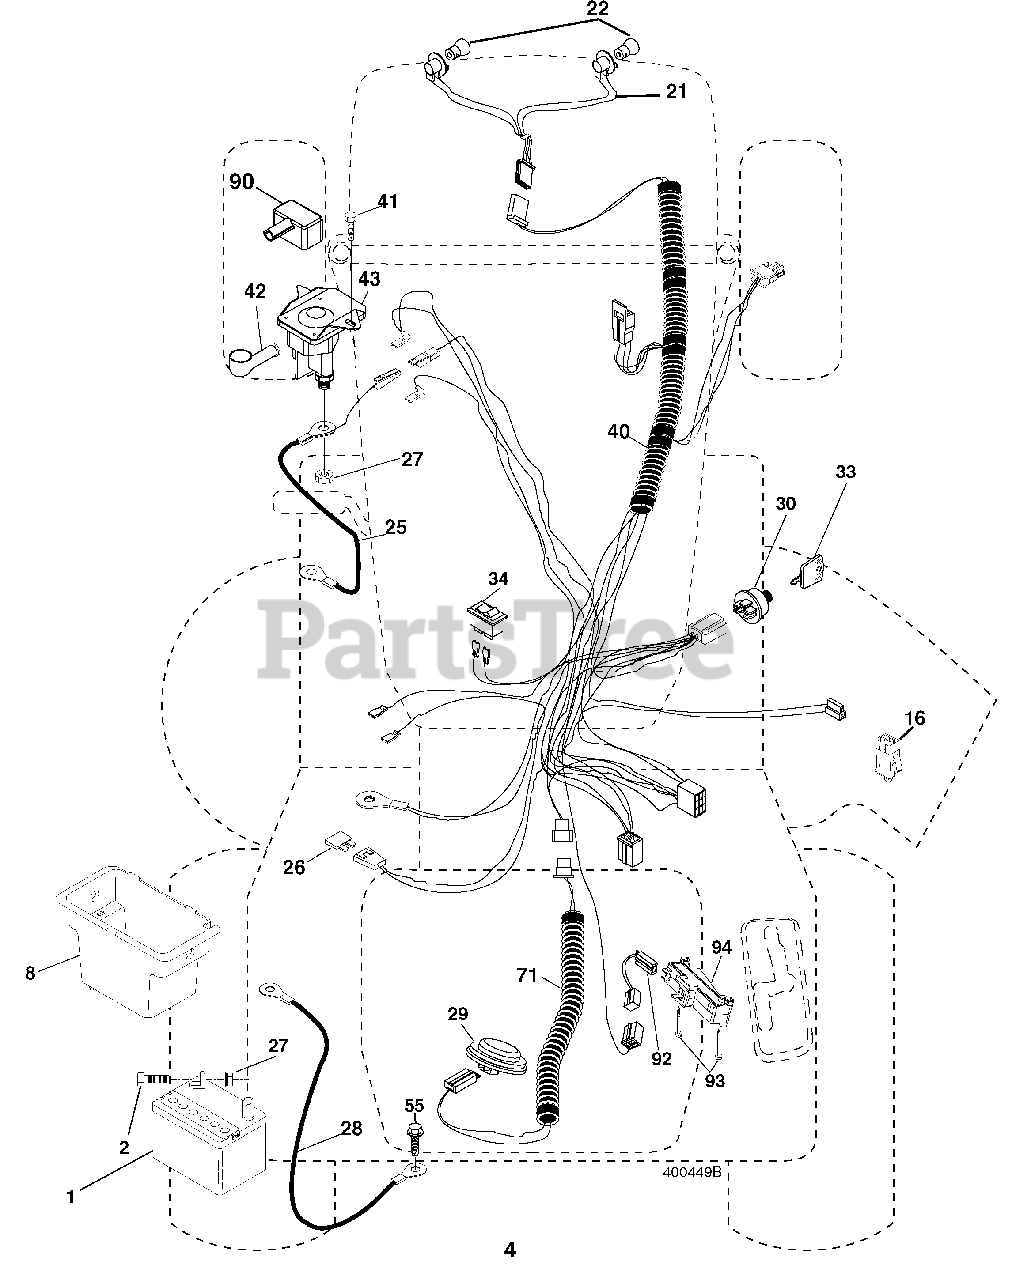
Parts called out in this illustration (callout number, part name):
1	Battery
2	Bolt Hex Hd 1/4-20 unc x 3/4
8	Box Battery
16	Switch Interlock
21	Harness Socket Light
22	Bulb, Light # 1156
25	Cable Battery 6 Ga. Red 14.5
26	Fuse
27	Nut Keps Hex 1/4-20 unc
28	Cable Ground 18" Rear Battery Blk 6 Ga.
29	Switch Seat
30	Switch Ign
33	Key Ign Molded Generic
34	Switch Light/Reset
40	Harness Ign
41	Screw 1/4-20 unc x 1/2
42	Cover Terminal Red
43	Solenoid
55	Screw 5/16-18 x 3/4
71	Harness Ign. Chass.
90	Cover Terminal
92	Harness Pigtail Reverse Switch
93	Screw Plastic 10-14 x 2.0
94	Modual Reverse ROS
